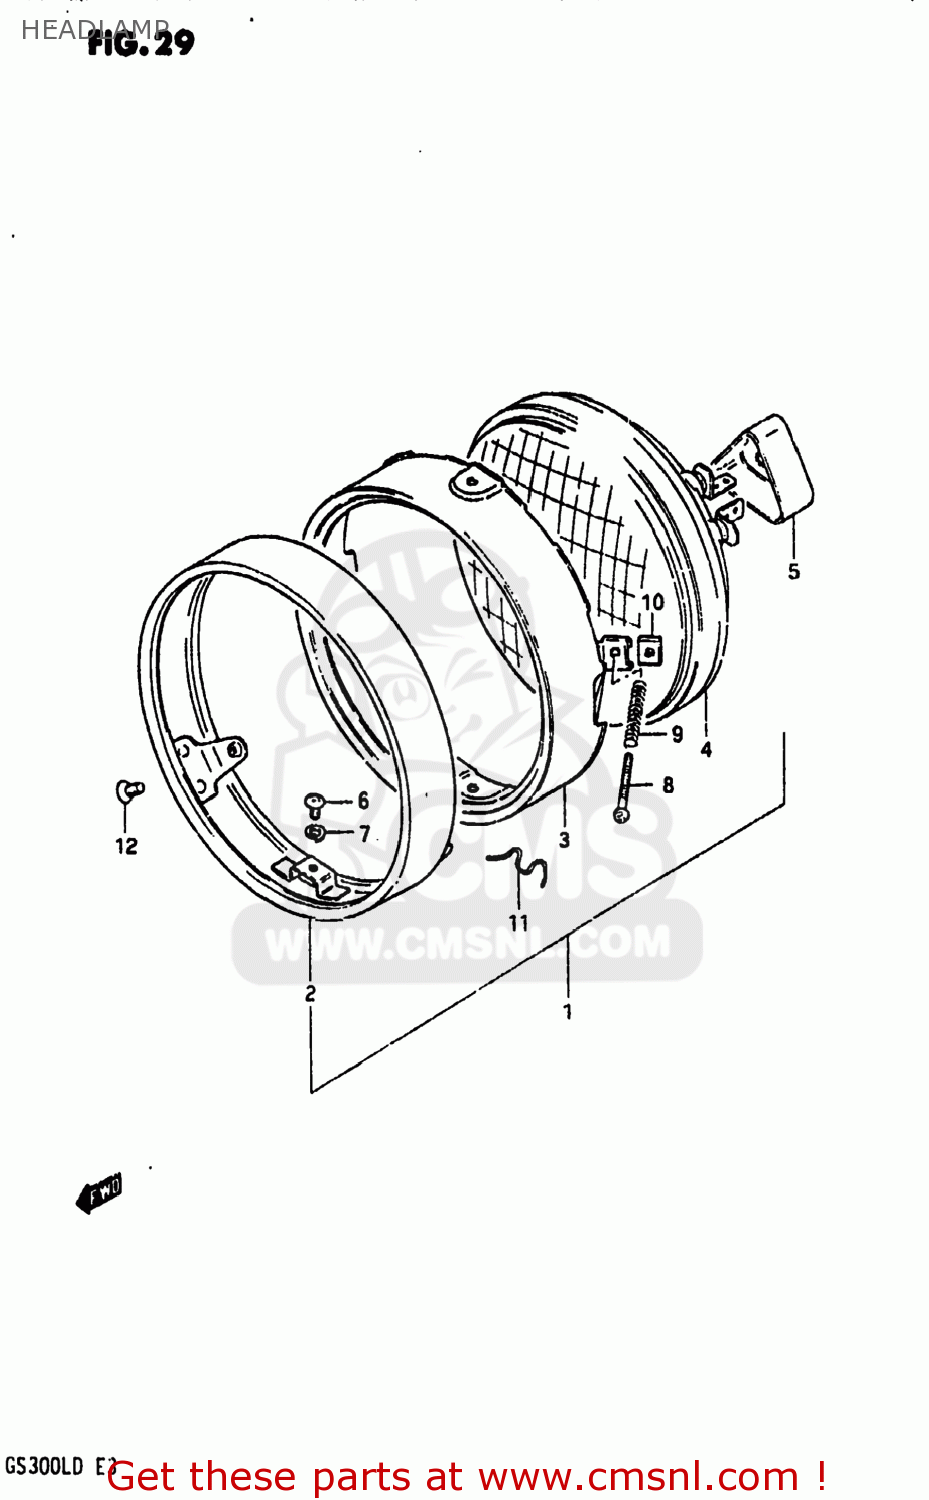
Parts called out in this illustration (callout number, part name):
1	LAMP ASSEMBLY,HEAD
2	RIM
3	RETAINER
4	LAMP UNIT
5	COVER
6	SCREW
7	LOCK WASHER
8	SCREW
9	SPRING
10	NUT
11	SPRING,HEAD LAMP UNIT
12	SCREW(5X12)
